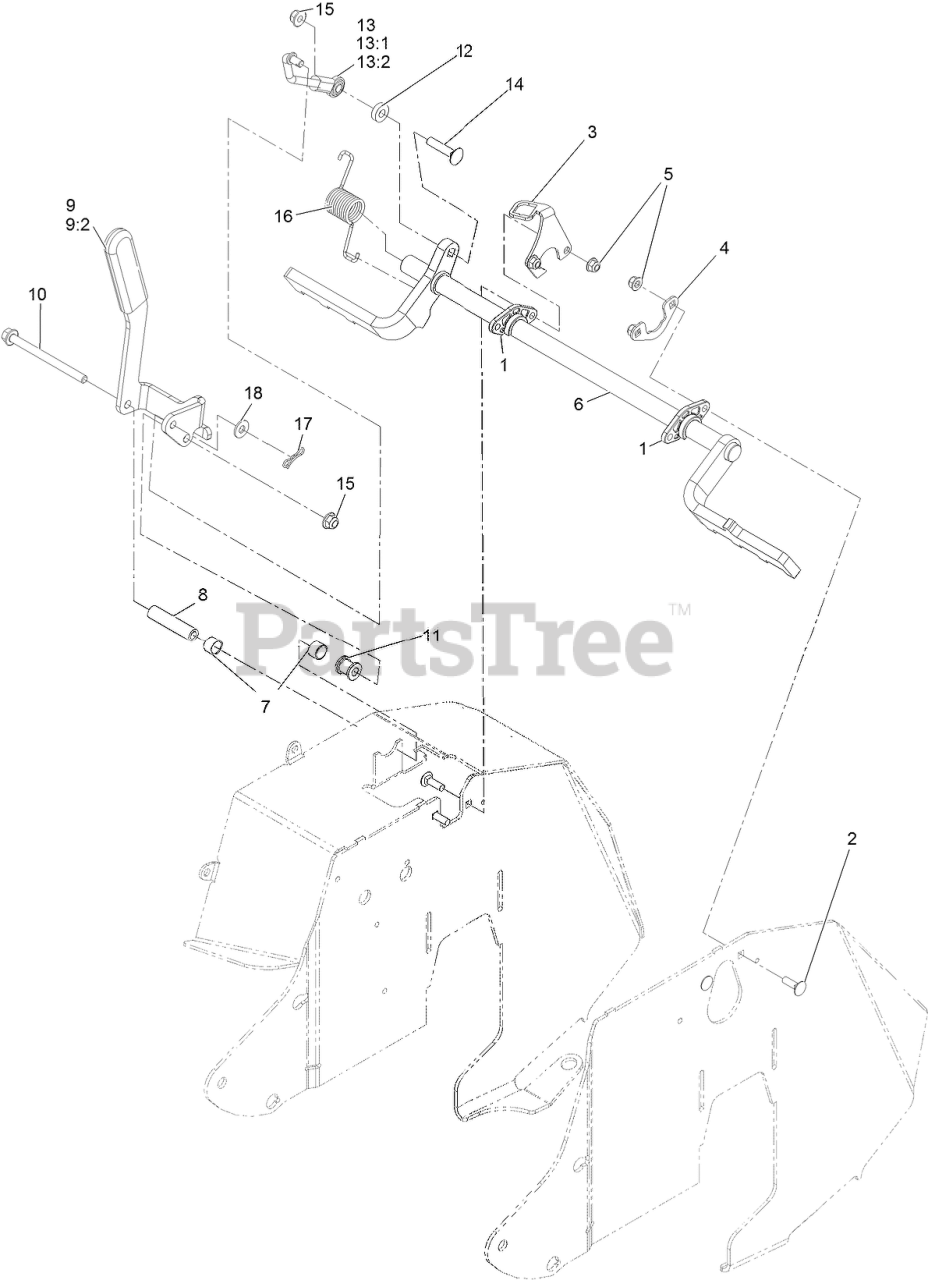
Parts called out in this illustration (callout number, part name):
1	BUSHING-FLANGE
2	BOLT-CARR
3	Bracket-Switch
4	SUPPORT, BEARING
5	NUT-HF, NI
6	Wld-Brake Shaft 32/36
7	SLEEVE-BUSHING
8	BUSHING-PIVOT
9	ASM-Brake Lever With Grip
9:2	GRIP-LEVER
10	SCREW-HF
11	Spacer-.39Idx.88Odx.88L
12	SPACER
13	ASM-Brake Link
13:1	JOINT-BALL, END
13:2	Rod-Brake
14	SCREW-CARR
15	NUT-HF, NI
16	SPRING-TORSION
17	PIN-COTTER, LOCKING
18	WASHER-FLAT
